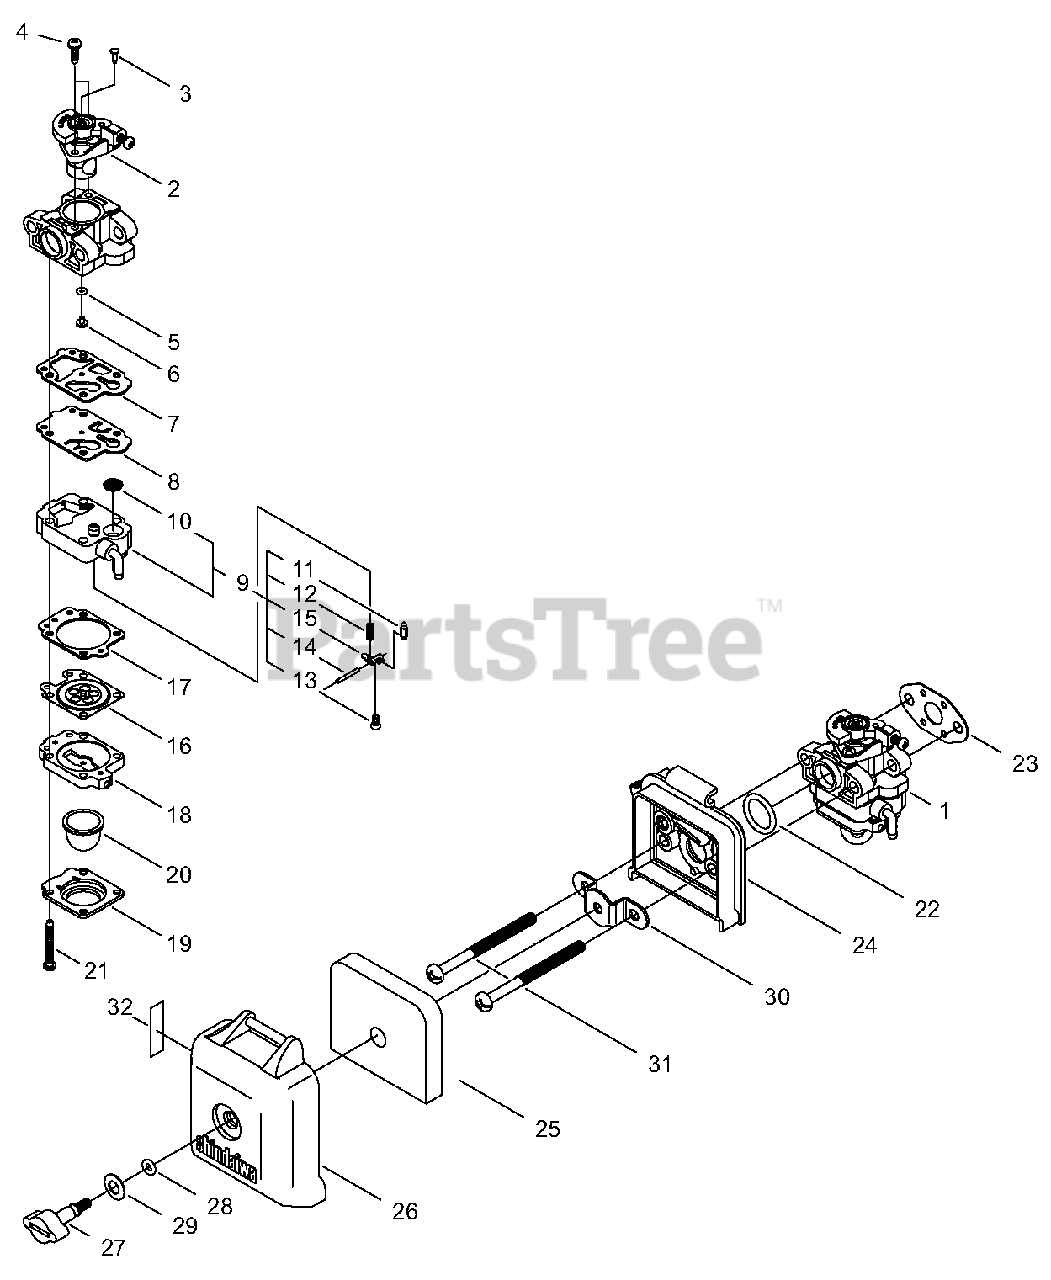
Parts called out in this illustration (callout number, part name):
1	CARBURETOR
2	VALVE ASSY, THROTTLE
3	PLUG
4	SCREW, THROTTLE COLLAR
5	O-RING
6	JET, MAIN #40
7	GASKET, PUMP
8	DIAPHRAGM, FUEL PUMP
9	BODY ASSY, PUMP
10	SCREEN, FUEL INLET
11	VALVE, INLET NEEDLE
12	SPRING, METERING LEVER
13	SCREW
14	PIN, METERING LEVER
15	LEVER, METERING
16	DIAPHRAGM, METERING
17	GASKET, METERING DIAPHRAGM
18	BODY ASSY, PURGE
19	RETAINER, PURGE BULB
20	BULB, PURGE
21	SCREW
22	O-RING 15
23	GASKET, CARBURETOR
24	CASE, AIR FILTER
25	FILTER, AIR
26	COVER, AIR FILTER
27	THUMBSCREW
28	O-RING
29	WASHER, CONE M6
30	BRACKET
31	SCREW M5×60
32	LABEL, CHOKE
